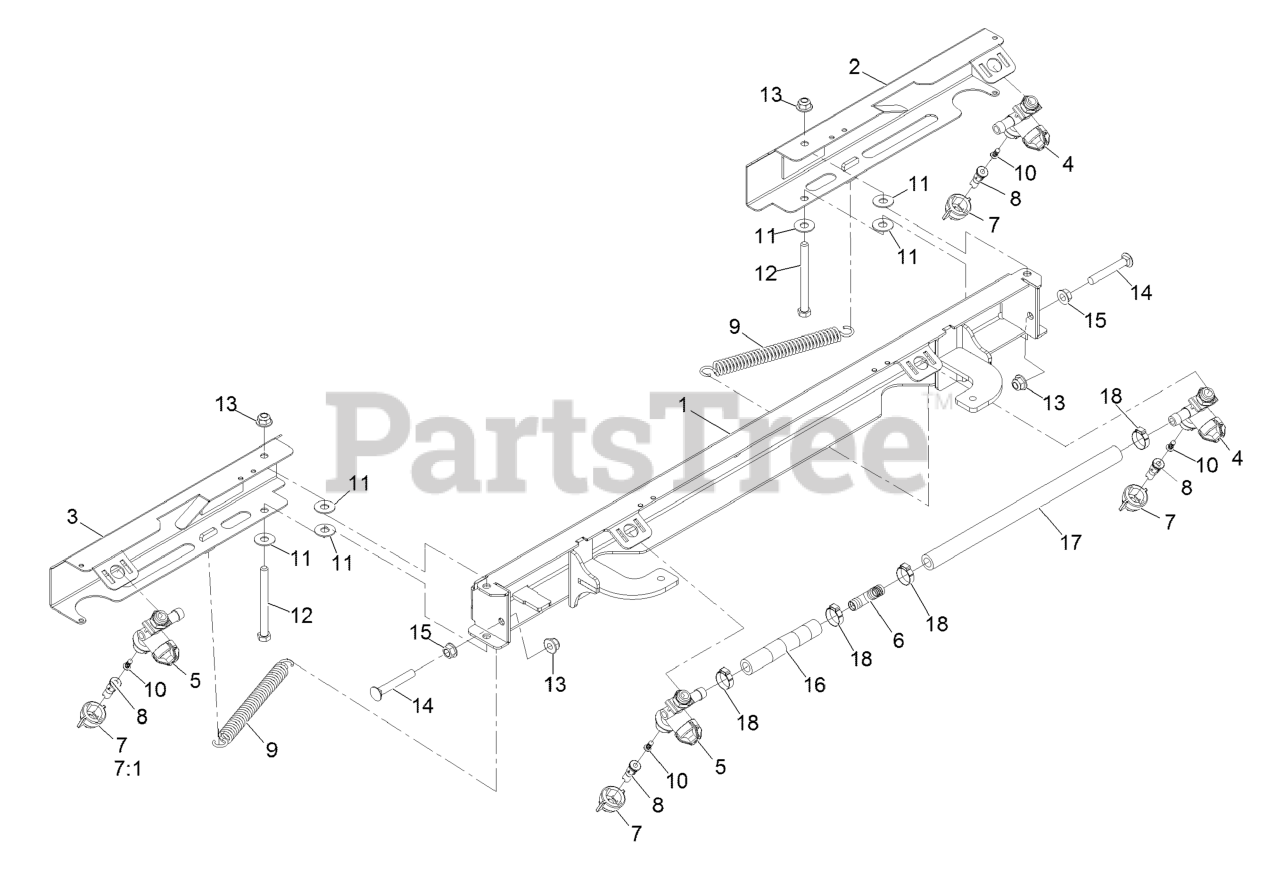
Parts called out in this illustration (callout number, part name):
1	Boom-Center
2	Boom-Wing, Rt
3	Boom-Wing, Lt
4	BODY-NOZZLE, RIGHT
5	BODY-NOZZLE, LEFT
6	FITTING-TEE, BARB
7	CAP-NOZZLE
7:1	SEAT-GASKET
8	TIP-SPRAY, 025
9	SPRING-EXTENSION
10	STRAINER-NOZZLE, 50M 5PSI
11	WASHER-FLAT
12	SCREW-HH
13	Nut-Hex Flange
14	SCREW-CARR
15	Nut-Hex Flange
16	Hose-Spray
17	Hose-Spray
18	CLAMP-OETIKER, 167
